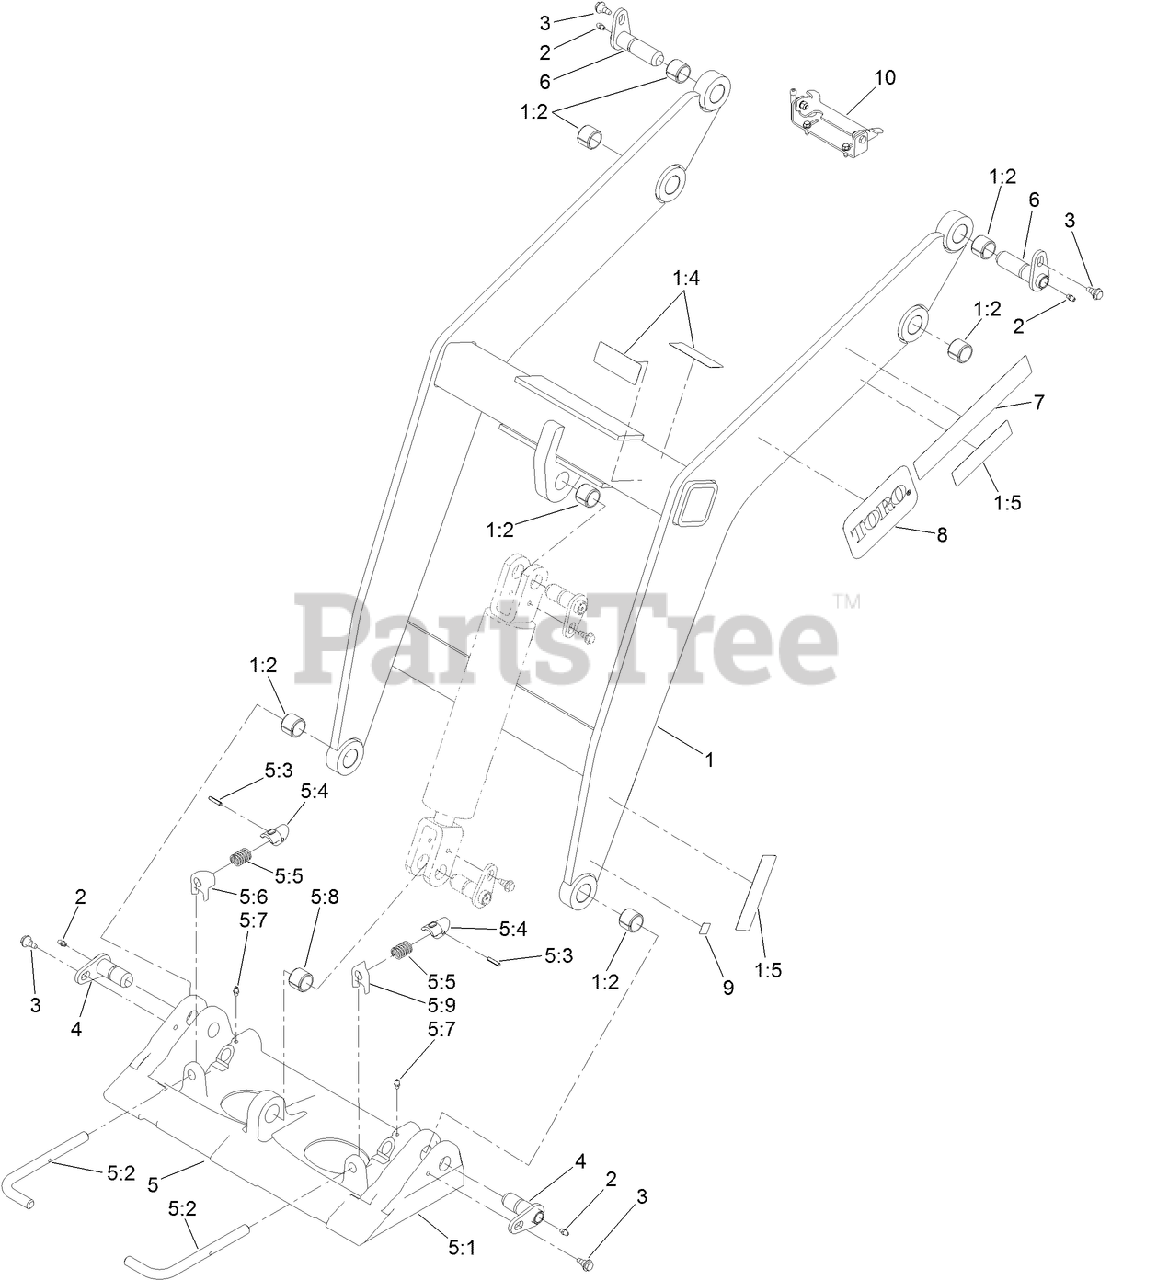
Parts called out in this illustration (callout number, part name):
1	LOADER ASM
1:2	BUSHING-TENSION
1:4	DECAL-WARNING, CRUSHING
1:5	DECAL-WARNING, NO RIDER
2	FITTING-GREASE
3	BOLT-SHOULDER
4	PIN-PIVOT
5	QUICK ATTACH ASM
5:1	MOUNT-QTACH
5:2	PIN-LOCKING
5:3	PIN-GROOVED
5:5	SPRING-COMPRESSION
5:6	STOP-RH
5:7	FITTING-GREASE
5:8	BUSHING-TENSION
5:9	STOP-LH
6	PIN-PIVOT
8	DECAL
9	DECAL-POINT, LIFT
10	LEVER LOCK ASM
